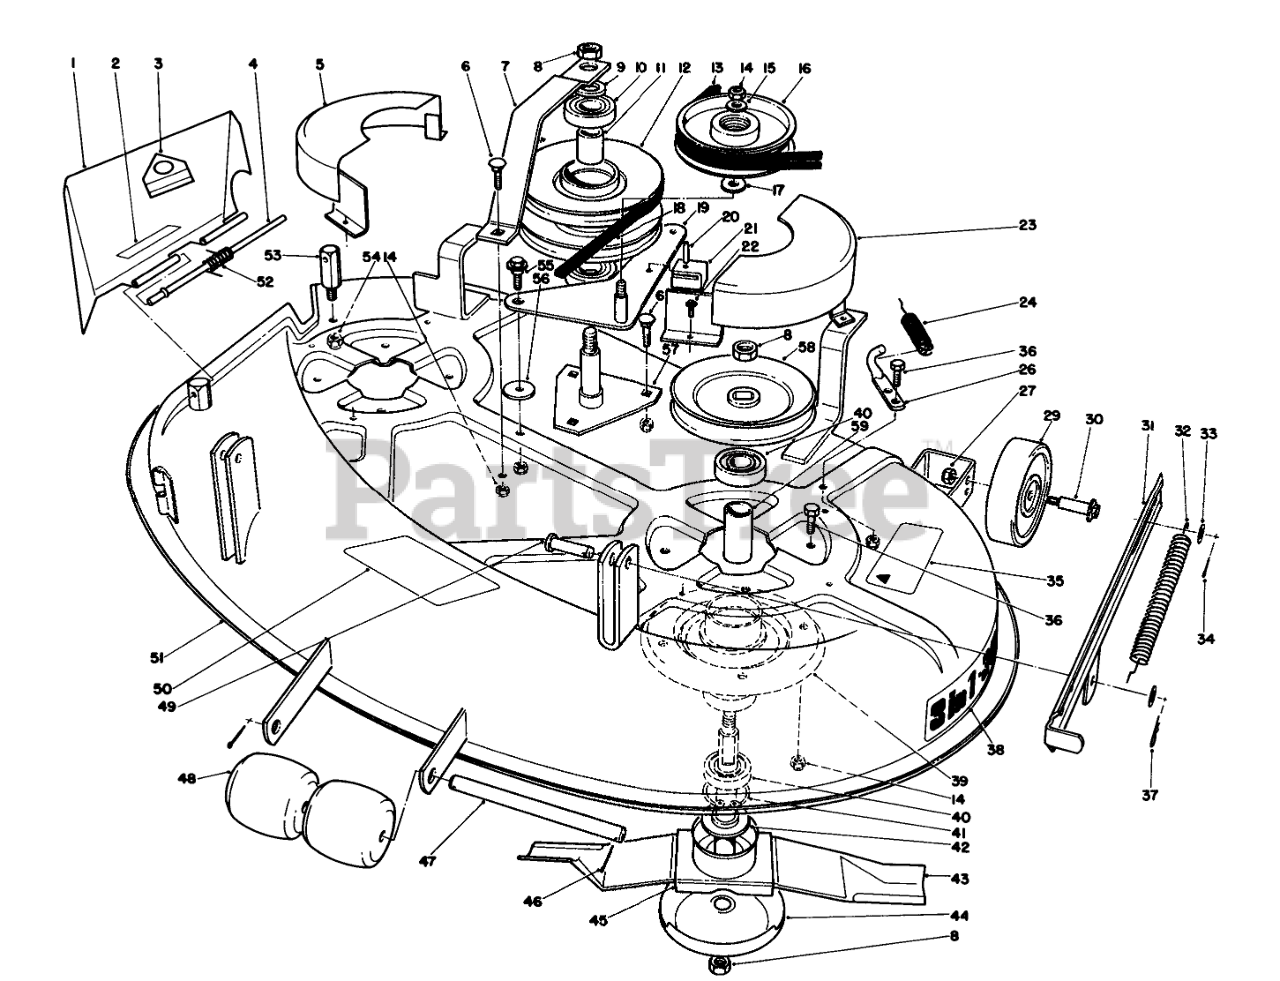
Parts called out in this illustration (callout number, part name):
1	Deflector Assembly (Incl. Ref. #2-3)
2	DECAL-NO STEP
3	DECAL-DANGER
4	ROD-HINGE DEFLECTOR
5	RH BELT COVER WA B
6	BOLT-CARR
7	Support-Pulley
9	WASHER-FLAT
10	BEARING-BALL
11	TUBULAR SPACER
12	Pulley Assembly (Incl. Ref. #10-11)
13	V-BELT
14	NUT-LOCK, NI
15	WASHER-FLAT
16	PULLEY-IDLER
17	WASHER-FLAT
18	V-BELT
19	Bracket-Idler
20	PIN-COIL
21	IDLER BRKT GUIDE
22	SCREW-HWHTF
23	Cover-Belt L.H.
24	DECK TENSION SPRNG O
26	SPRING ROD
27	NUT-LOCK, NI
29	WHEEL-DECK
30	BOLT-WHEEL
31	Strap-Deck Spring (L.H.)
32	DECK TENSION SPRNG O
33	WASHER-FLAT
34	PIN-COTTER
35	DECAL-CAUTION, BLADE
36	SCREW-HH
37	PIN-COTTER
38	DECK DECAL
39	Spindle
40	BEARING-BALL
41	RING-RETAINING
42	SPACER-SPINDLE
43	Blade
44	Cup
45	Shaft-Spindle
46	PIN-COTTER
47	Shaft-Roller
48	Roller
49	PIN-CLEVIS
50	Decal-Belt Routing
51	Deck-38"
52	SPRING
53	REAR PIVOT POST (PLTD)
54	NUT-LOCK, NI
55	SCREW-SHOULDER
56	WASHER-PIVOT
57	Jackshaft
58	DECK PULLEY
59	BEARING SPACER
